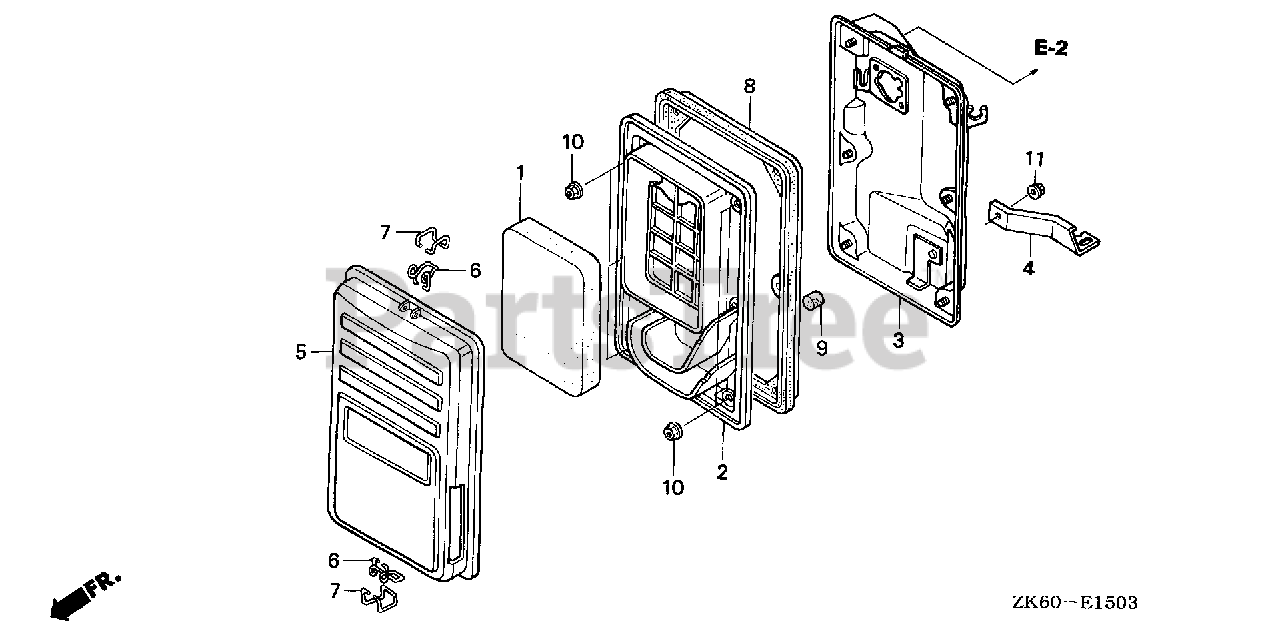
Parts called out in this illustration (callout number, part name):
1	ELEMENT, AIR CLEANER
2	SEPARATOR, AIR CLEANER
3	HOUSING, AIR CLEANER
4	STAY, AIR CLEANER
5	COVER, AIR CLEANER
6	CLIP A, AIR CLEANER WIRE
7	CLIP B, AIR CLEANER WIRE
8	SEAL, AIR CLEANER
9	FILTER, DRAIN TUBE
10	NUT, FLANGE (5MM)
11	NUT, FLANGE (6MM)
